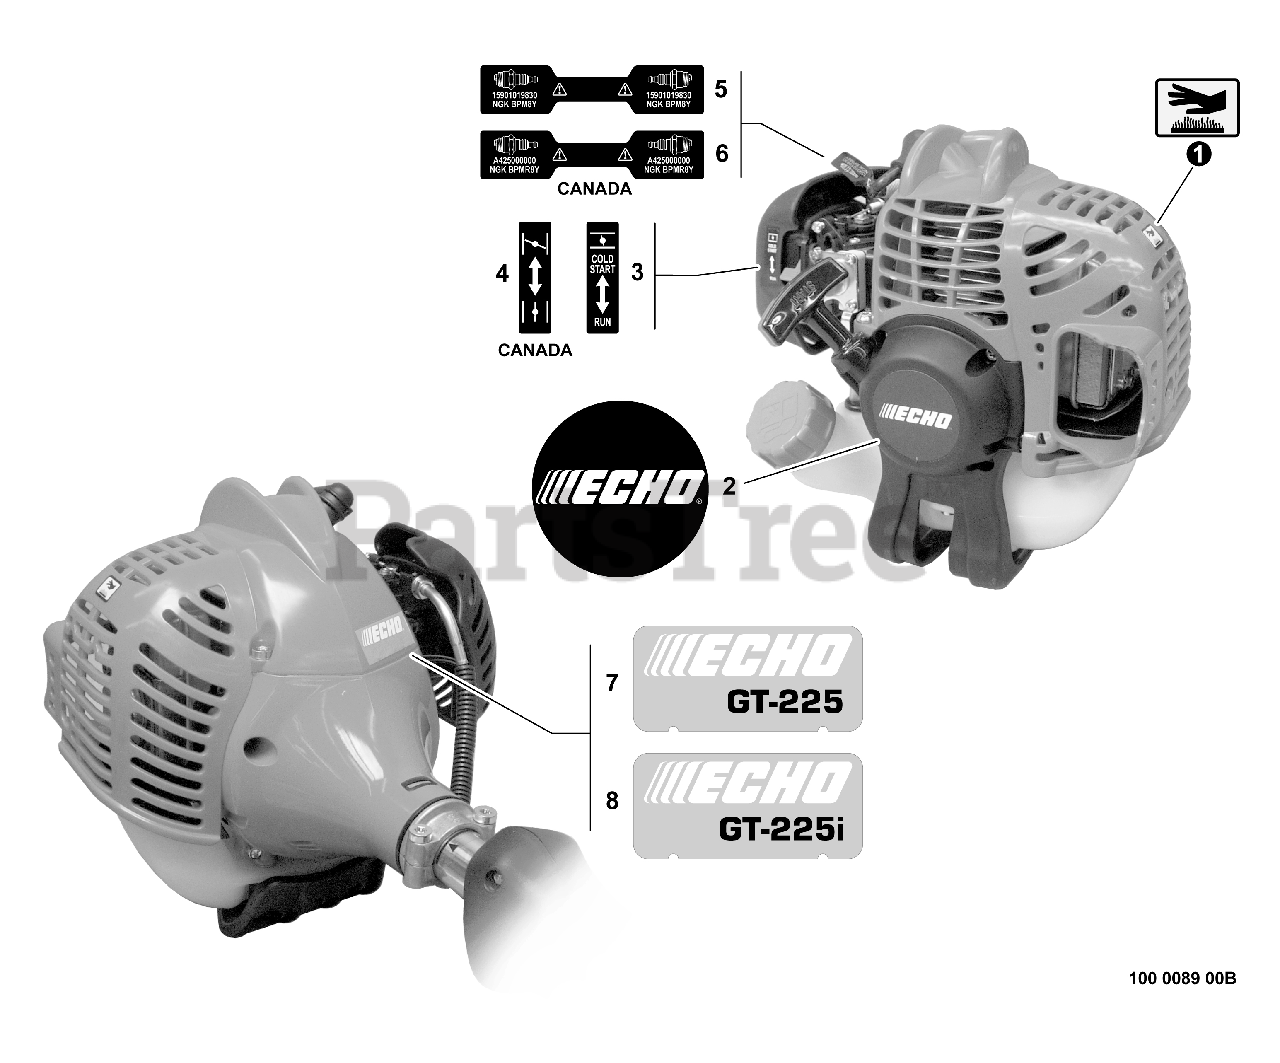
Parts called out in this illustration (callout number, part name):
1	LABEL - HOT SURFACE
2	LABEL - ECHO
3	LABEL - CHOKE
4	LABEL - CHOKE
5	LABEL - SPARK PLUG -- BPM-8Y
6	LABEL - SPARK PLUG -- BPMR-8Y
7	LABEL - MODEL GT-225
8	LABEL - MODEL GT-225i
